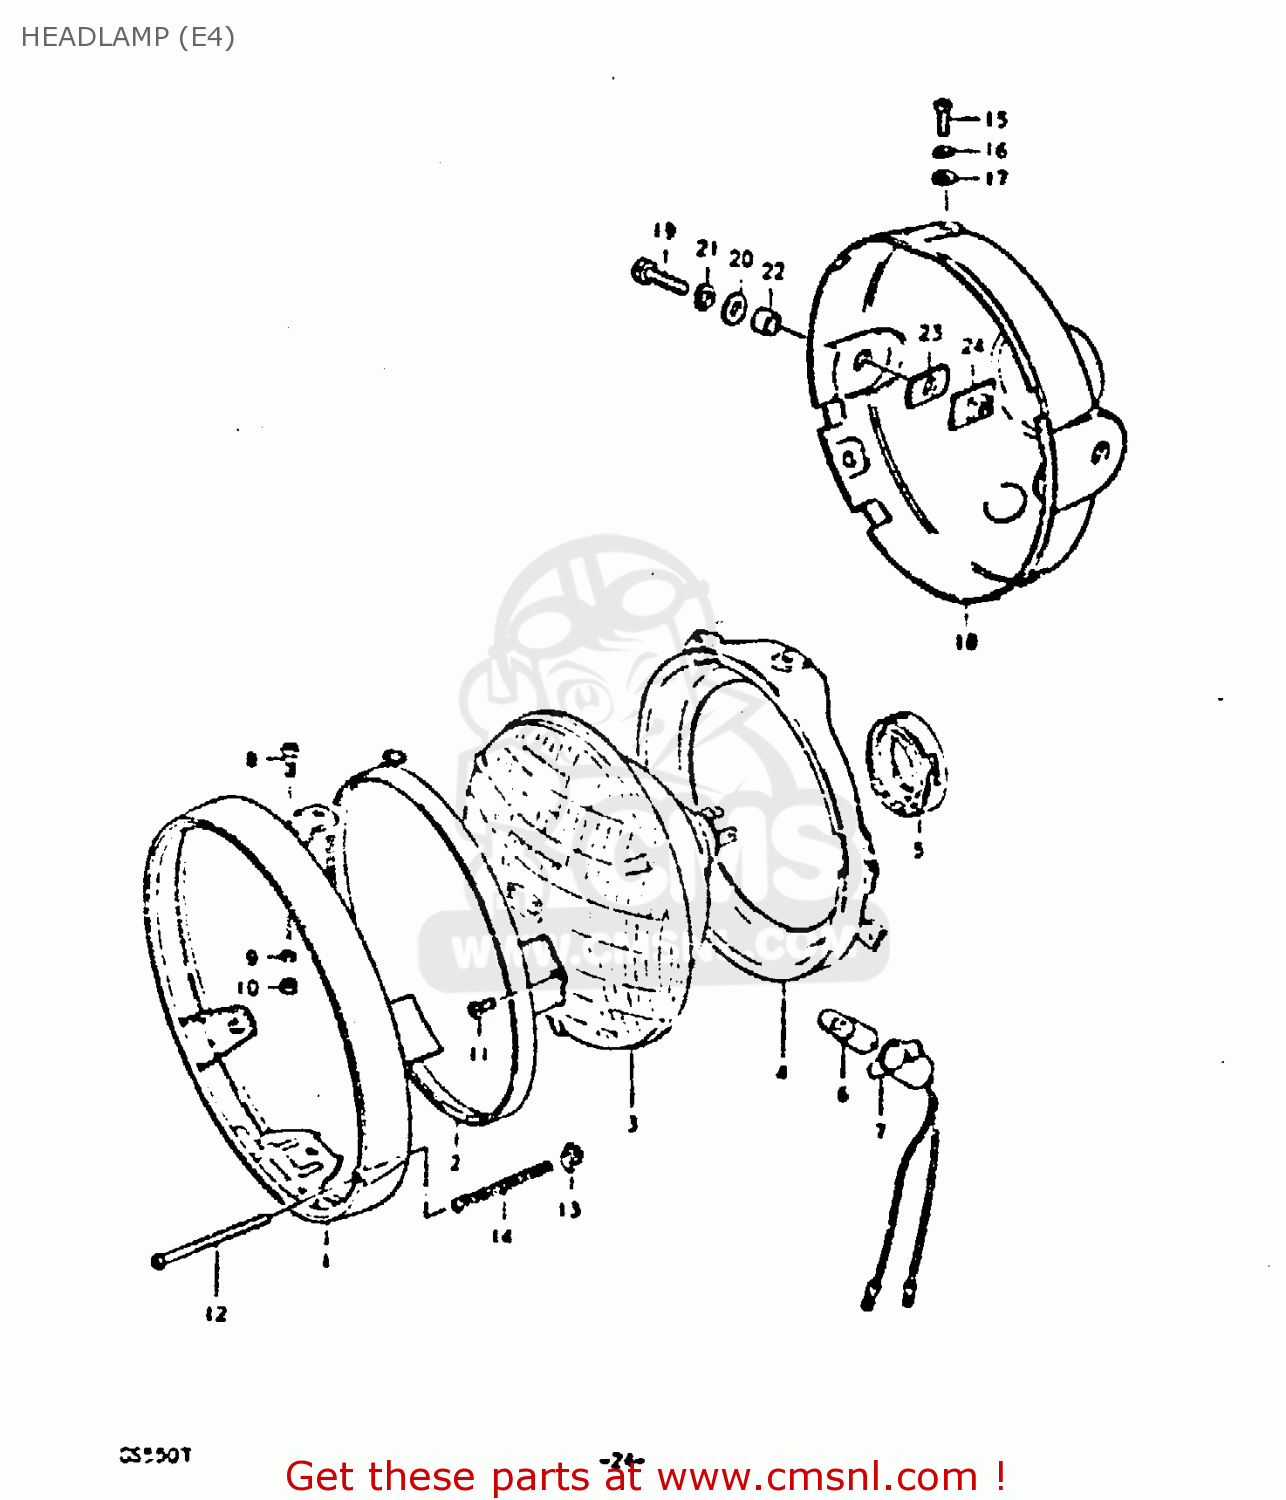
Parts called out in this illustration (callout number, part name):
1	RIM
2	RETAINING RING
3	LENS UNIT (12V, 45/40W)
4	RING
5	SETTER,BULB
6	BULB
7	SOCKET
8	H/LAMP LENS UNIT FITING SCRE
9	LOCK WASHER
10	NUT
11	SCREW
12	SCREW,HEADLAMP ADJUST
13	NUT
14	SPRING,ADJUSTING
15	SCREW
16	WASHER,LOCK
17	WASHER
18	HOUSING,HEADLAMP(BLACK)
19	BOLT
20	WASHER
21	LOCK WASHER
22	SPACER (8.8X12X7)
23	CUSHION
24	PLATE,HEADLAMP HOUSING
